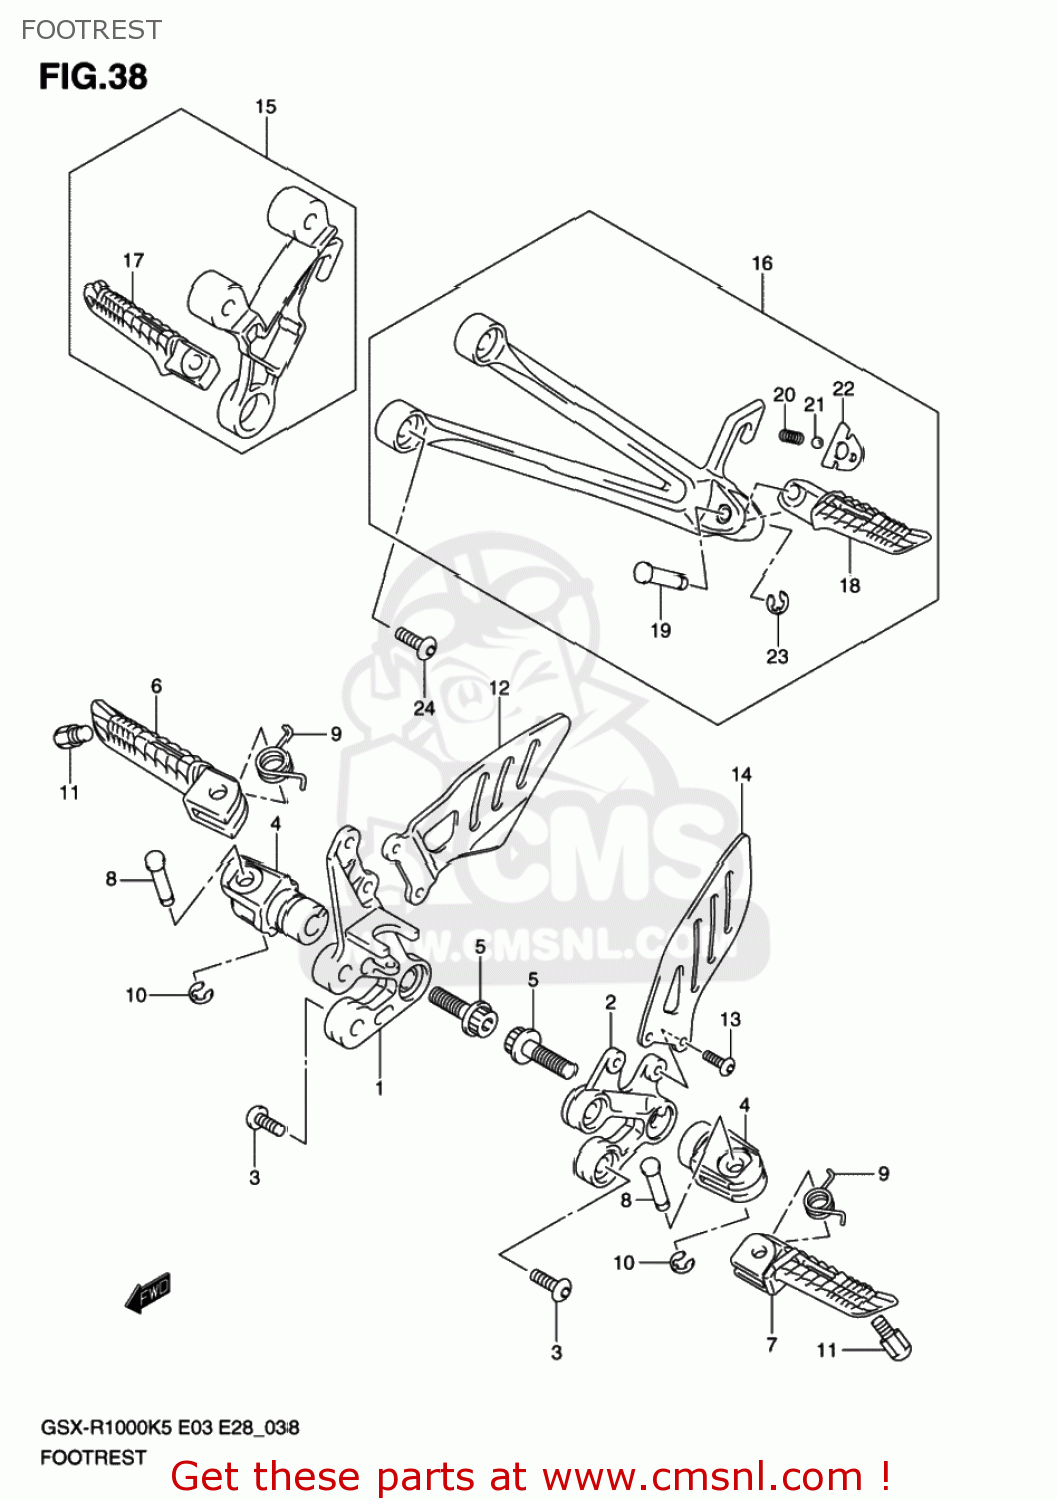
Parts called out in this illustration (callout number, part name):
1	BRACKET,FR FOOTREST,R
2	BRACKET,FR FOOTREST,L
3	BOLT(8X23)
4	HOLDER,FOOTRES
5	BOLT(10X28)
6	BAR,FR FOOTREST,R
7	BAR,FR FOOTREST,L
8	PIN(8X33.2)
9	SPRING
10	E.RING
11	BOLT,BANK SENSOR
12	GUARD, FOOTREST RH
13	SCREW,FOOTREST GUARD,L
14	GUARD,FRONT FO
15	FOOTREST ASSY,PILLION,R
16	FOOTREST ASSY,PILLION,L
17	BAR,PILLION FOOTREST,R
18	BAR,PILLION FOOTREST,L
19	PIN
20	SPRING
21	BALL
22	PLATE,PILLION FOOTREST
23	E.RING
24	BOLT(8X23)
